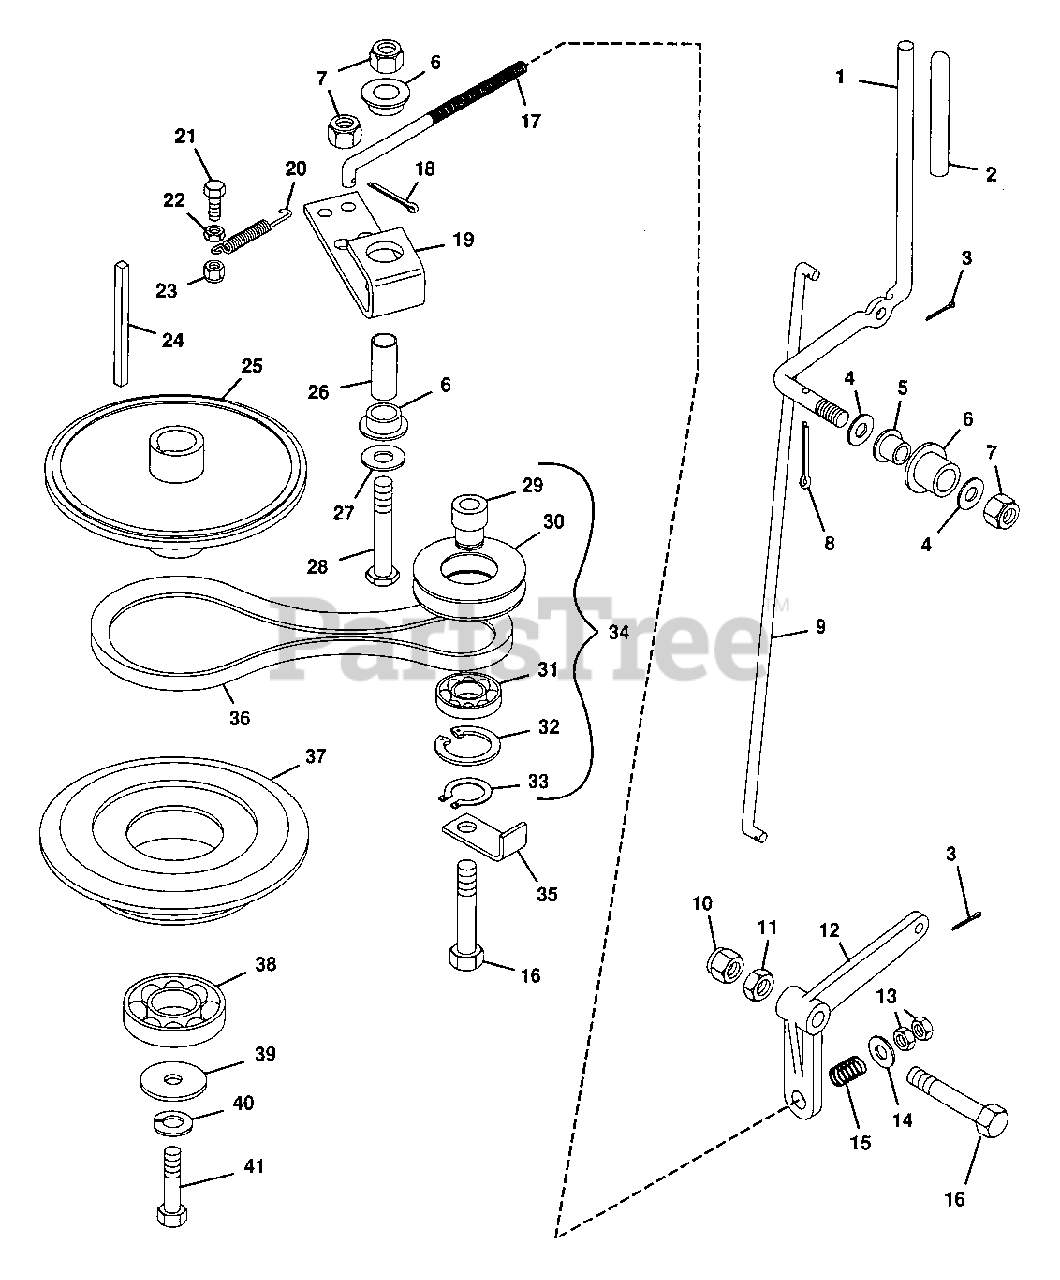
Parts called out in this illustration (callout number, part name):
1	Lever, PTO Actuating
2	Grip, PTO Lever
3	Pin, Cotter .09x.75
4	Washer, Flat .531x1.250x.100
5	Bush., Flg. .515x1.00x.745 Ny.
6	Bush., Flg. .764x1.47x.560 Ny.
7	Nut, Lock 1/2-13
8	Pin, Cotter .187x1.625
9	Rod, PTO Control
10	Nut, Lock 1/2-13
11	Nut, Jam 1/2-13 Hex
12	Lever, PTO Clutch
13	Nut, Hex 3/8-16
14	Washer, Flat .406x.812x.065
15	Spring, Comp. 1x.78x338
16	Bolt, Hex 1/2-13x2.50
17	Rod, PTO Clutch Actuating
18	Pin, Cotter .125x.75
19	Arm, Idler Pivot
20	Spring, PTO Return
21	Bolt, Hex 5/16-18x1.00
22	Nut, Hex 5/16-18
23	Nut, Lock 5/16-18
24	Key, Square .250x3.60
25	Hub, PTO Clutch
26	Bush., St. .560x.745x2.04 Stl.
27	Washer, Flat .531x1.062x.095
28	Bolt, Hex 1/2-13x2.75 Special
29	Bush., Flg. .515x.787x1.41 Stl.
30	Sheave, Idle
31	Bearing, Ball
32	Ring, Retaining
33	Ring, Retaining
34	Assembly, Idler Sheave
35	Guide, Belt
36	V-Belt, PTO Clutch
37	Sheave, Mower Clutch
38	Bearing, Ball 1.574x3.149x.708
39	Washer, Special
40	Washer, Lock 7/16 Reg.
41	Bolt, Hex 7/16-20x2.50
